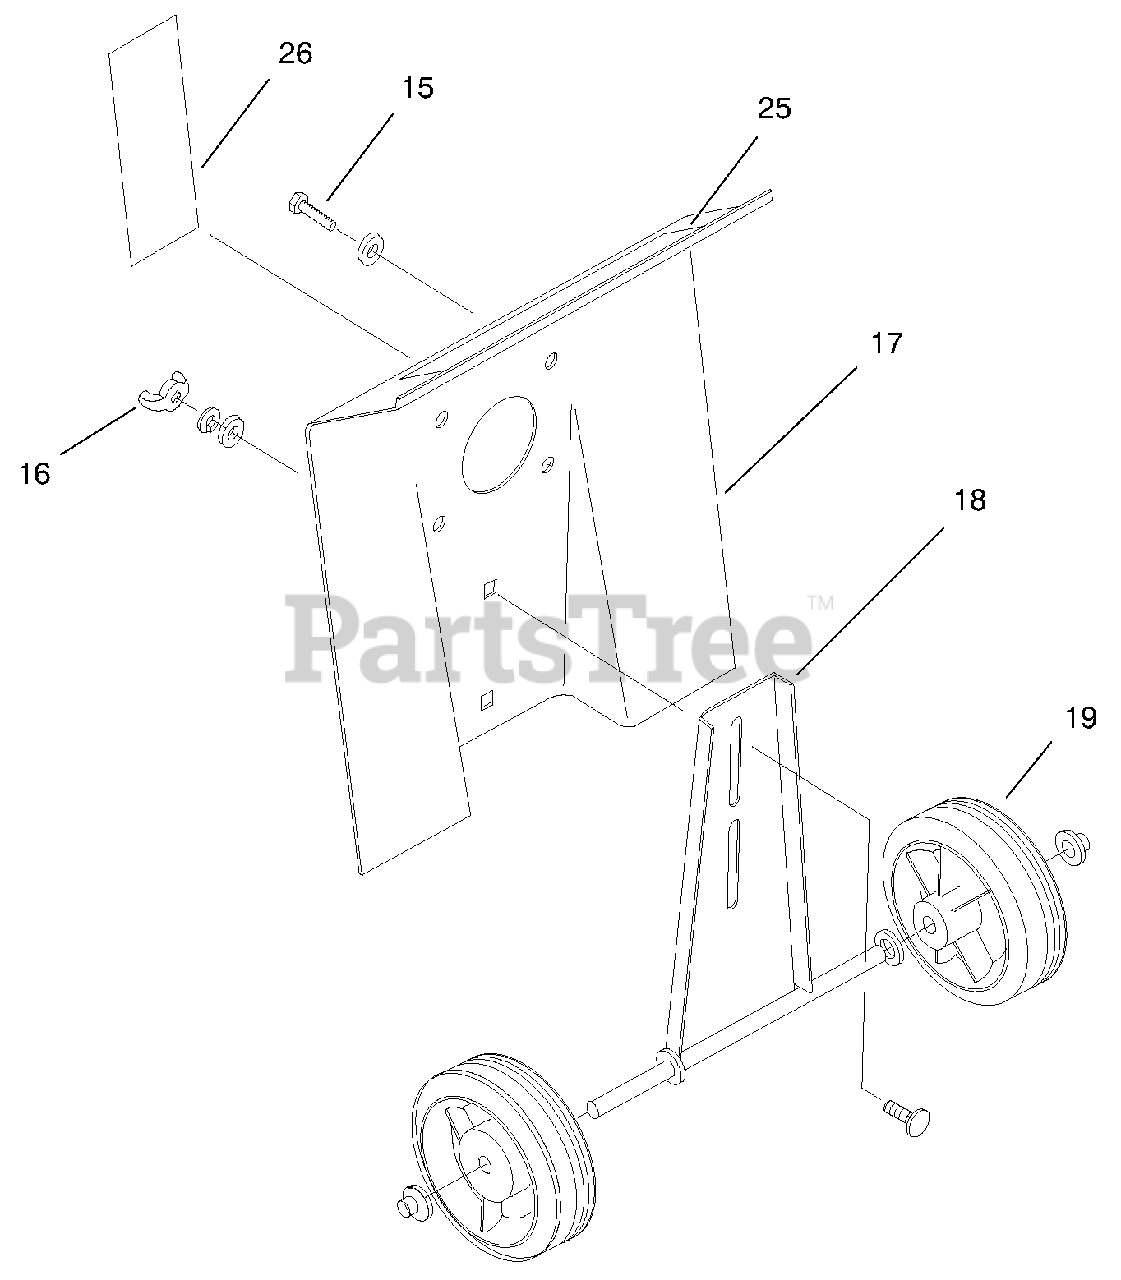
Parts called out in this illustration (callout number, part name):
15	Guard Mounting Hardware
16	Wheel Bracket Mounting Hardware
18	Wheel Bracket Asm.
19	Wheel Asm.
25	Decal-Tine Guard
26	Decal-Tiller Safety Symbol
